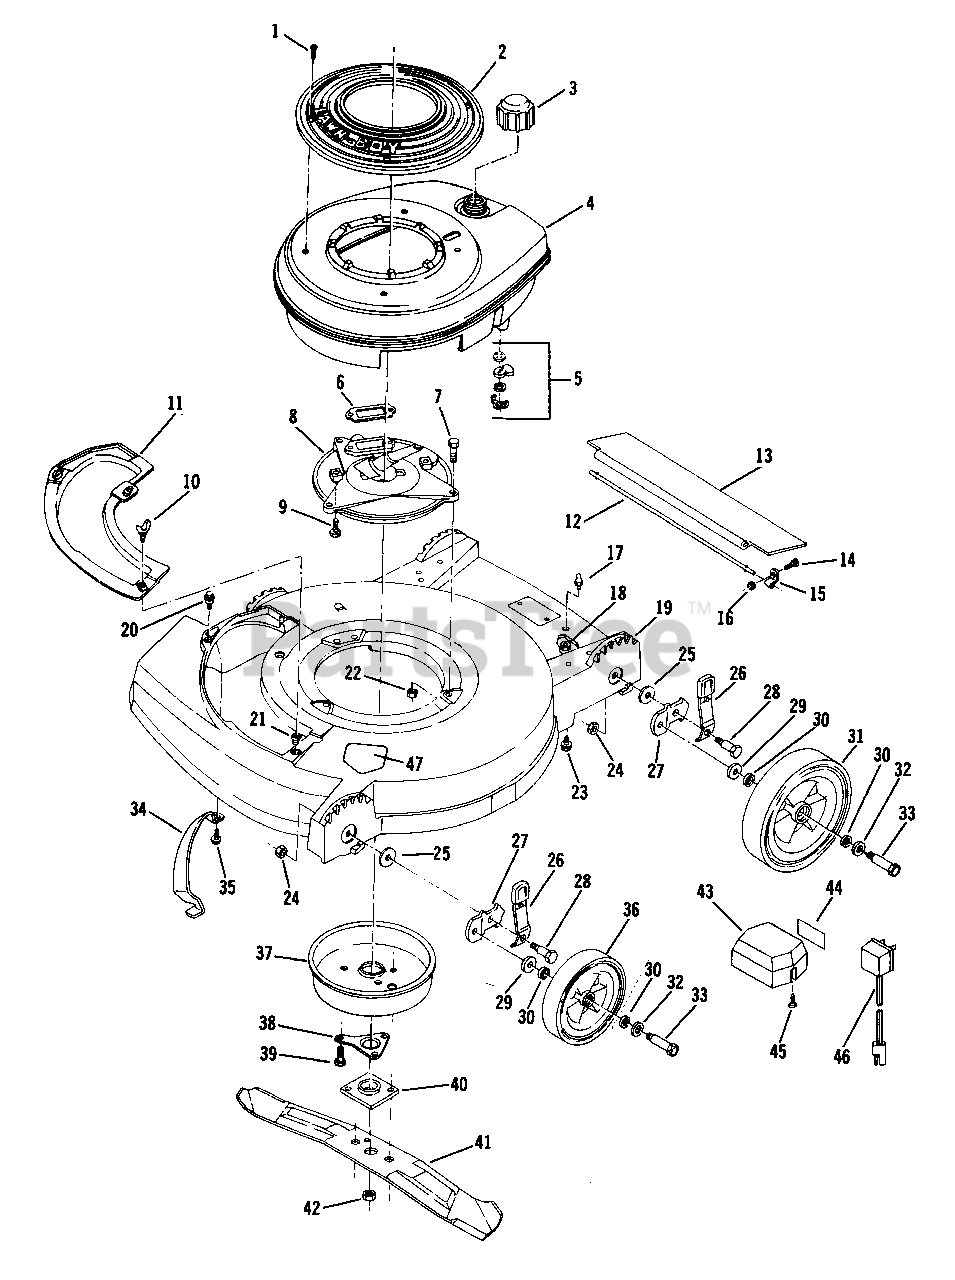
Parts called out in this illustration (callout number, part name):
1	Screw
2	Cover-Shroud
3	Fuel Cap
4	Shroud
5	Fuel Shut-Off Assembly
6	Gasket-Exhaust
7	Screw-Muffler Plate to Housing
8	Plate-Muffler
9	Screw-Muffler Plate to Block
10	Wing Screw
11	Cover Plate
12	Rod-Trailing Shield
13	Shield-Trailing
14	Screw
15	Clamp
16	Nut
17	Ball Stud-Batt. Mtg.
18	Nut-Ball Stud
19	Housing
20	Screw-Plate and Chute Mounting
21	Grommet
22	Nut-Muffler Plate to Housing
23	Screw
24	Nut
25	Washer
26	Knob and Spring Assembly
27	Bracket
28	Bolt-Shoulder
29	Washer
30	Washer-Felt
31	Wheel-Rear
32	Washer
33	Bolt-Wheel
34	Toe Bar
35	Screw
36	Wheel-Front
37	Muffler-Cover Assembly
38	Support-Crankshaft
39	Screw-Muffler to Muffler Plate
40	Collar and Plate Assembly
41	Blade-21"
42	Nut-Blade
43	Batt. Box and Batt. Pack Assembly
44	Decal
45	Screw
46	Battery Charger Assembly
47	Decal-Blade Contact Warning
